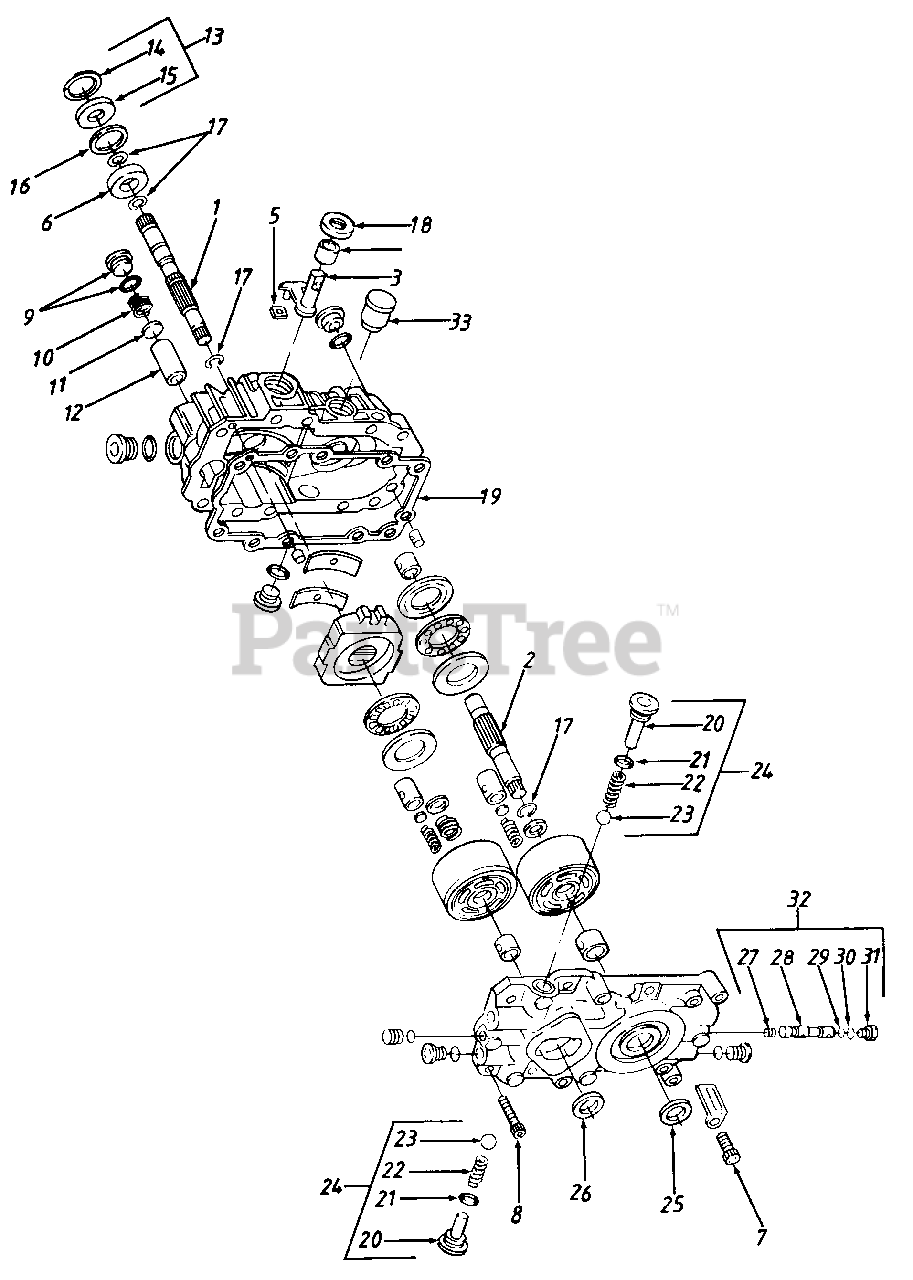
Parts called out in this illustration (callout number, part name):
1	Shaft-Pump
3	Arm, Trunnion
5	Guide, Slot
6	Bearing, Ball
7	Screw, Socket Head
8	Screw, Socket Head
9	Plug
10	Spring, Filter
11	Washer, Filter
12	Filter
13	Kit, Seal
14	Ring, Retaining
15	Seal, Lip
16	Spacer
17	Ring, Retaining
18	Seal, Lip
19	Gasket
21	O-Ring
22	Spring
24	Kit, Check Valve
25	Seal, Lip
26	Seal, Lip
27	Spring
29	O-Ring
30	O-Ring
32	Kit, Bypass Valve
33	Resevoir
